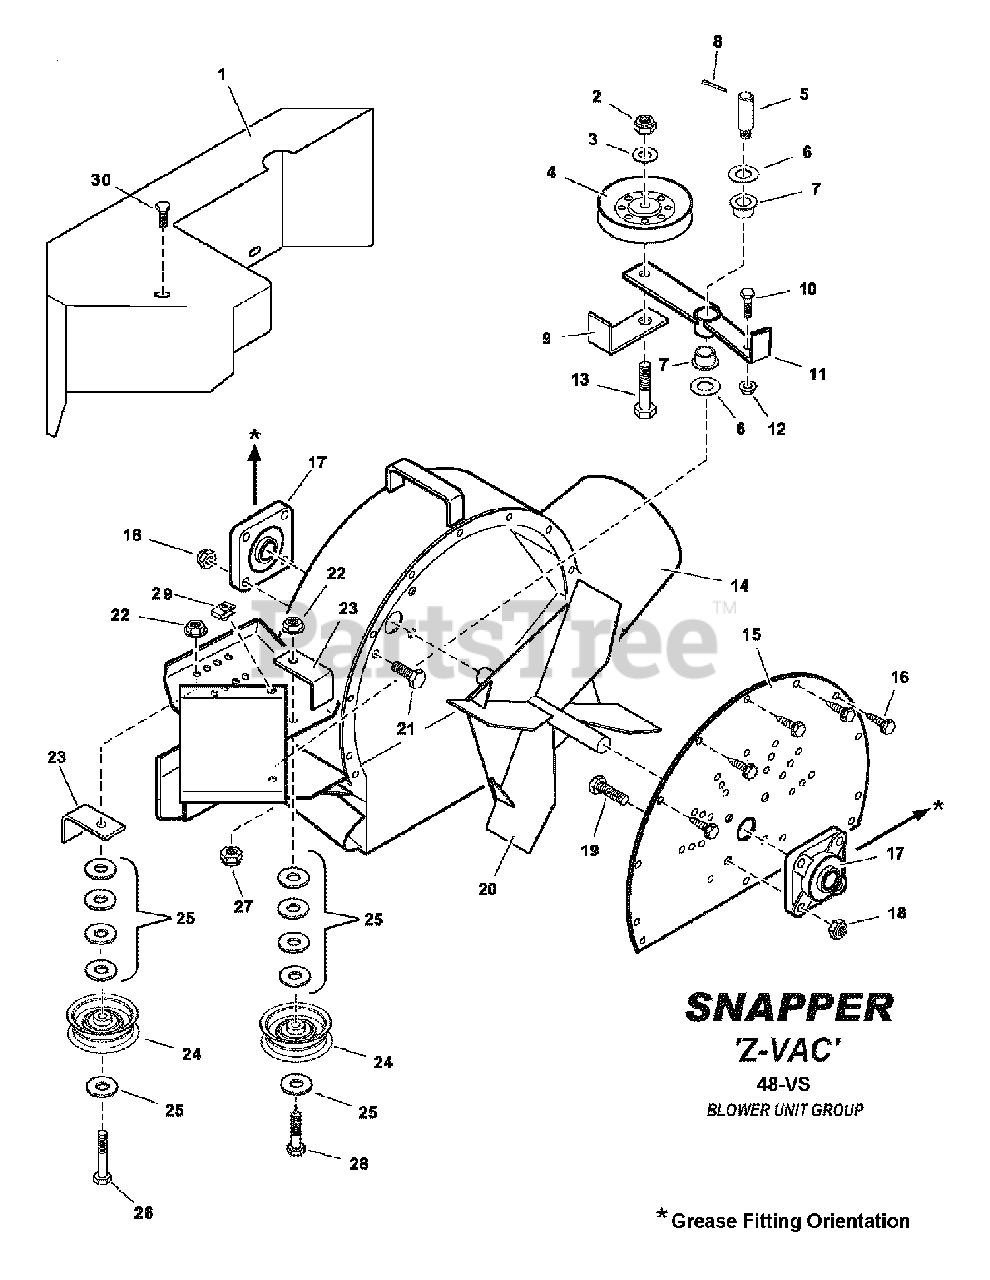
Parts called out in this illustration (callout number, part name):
1	WELDMENT, Blower Belt Guard
2	NUT, 1/2-13 Hex Nyloc
3	* WASHER, 1/2" Flat SAE
4	PULLEY, A Groove Idler, Steel
5	IDLER STUD (3/8-24 thread)
6	FLAT WASHER, 9/16 Type Narrow
7	FLANGE BEARING, 9/16" I.D. (powdered metal)
8	PIN, 1/8 x 3/4" Cotter
9	BELT RETAINER, Idler
10	SCREW, 5/16-18 x 1-1/4" Hex Head Cap, GR5
11	WELDMENT, Idler Arm
12	NUT, 5/16-18 Hex Flange Lock
13	SCREW, 1/2-13 x 2-1/2" Hex Head Cap, GR5
14	WELDMENT, Blower Housing
15	BACK PLATE, Blower
16	SCREW, 5/16-18 x 3/4" Hex Washer Self-Tap
17	BEARING, Pillow Block, Blower
18	NUT, 7/16-14 Hex Center Lock, GR5 or B
19	SCREW, 7/16-14 x 1-1/2" Hex Head Cap, GR5
20	IMPELLER, Fast Vac Blower (weldment)
21	SCREW, 7/16-14 x 1-1/4" Hex Head Cap, GR5
22	NUT, 3/8-16 Hex Flange Lock
23	BELT RETAINER
24	PULLEY, Flat Idler, 2-3/4" O.D.
25	WASHER, 3/8" Flat SAE
26	SCREW, 3/8-16 x 2-1/4" Hex Head Cap, GR5
27	NUT, 3/8-24 Hex Nyloc
28	SCREW, 3/8-16 x 2" Hex Head Cap, GR5
29	U-CLIP, 5/16-18
30	SCREW, 5/16-18 x 3/4" Hex Washer Self-Tap
